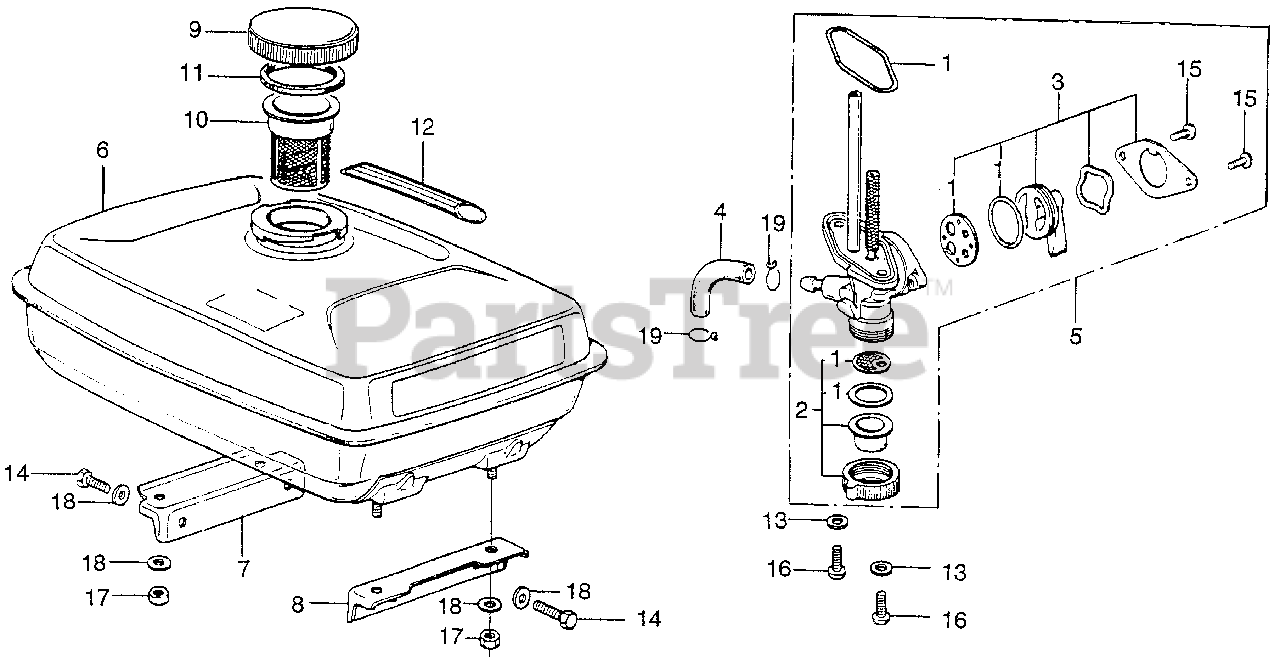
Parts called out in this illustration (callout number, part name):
1	GASKET SET, VALVE
2	CUP SET, STRAINER
3	LEVER SET, VALVE (NOT AVAILABLE)
4	TUBE, FUEL
5	PETCOCK ASSY.
6	TANK, FUEL *NH31* (MCKINLEY WHITE) (NOT AVAILABLE)
7	STAY A, FUEL TANK *R8* (BRIGHT RED)
8	STAY B, FUEL TANK *R8* (BRIGHT RED)
9	CAP, FUEL TANK (NOT AVAILABLE)
10	FILTER, FUEL
11	GASKET, FUEL FILTER (NOT AVAILABLE)
12	MARK A, CAUTION
13	GASKET, FIBER (6MM)
14	BOLT, HEX. (8X25)
15	SCREW, PAN (3X8)
16	SCREW, PAN (6X16)
17	NUT, HEX. (8MM)
18	WASHER, PLAIN (8MM)
19	CLIP, TUBE (B12)
